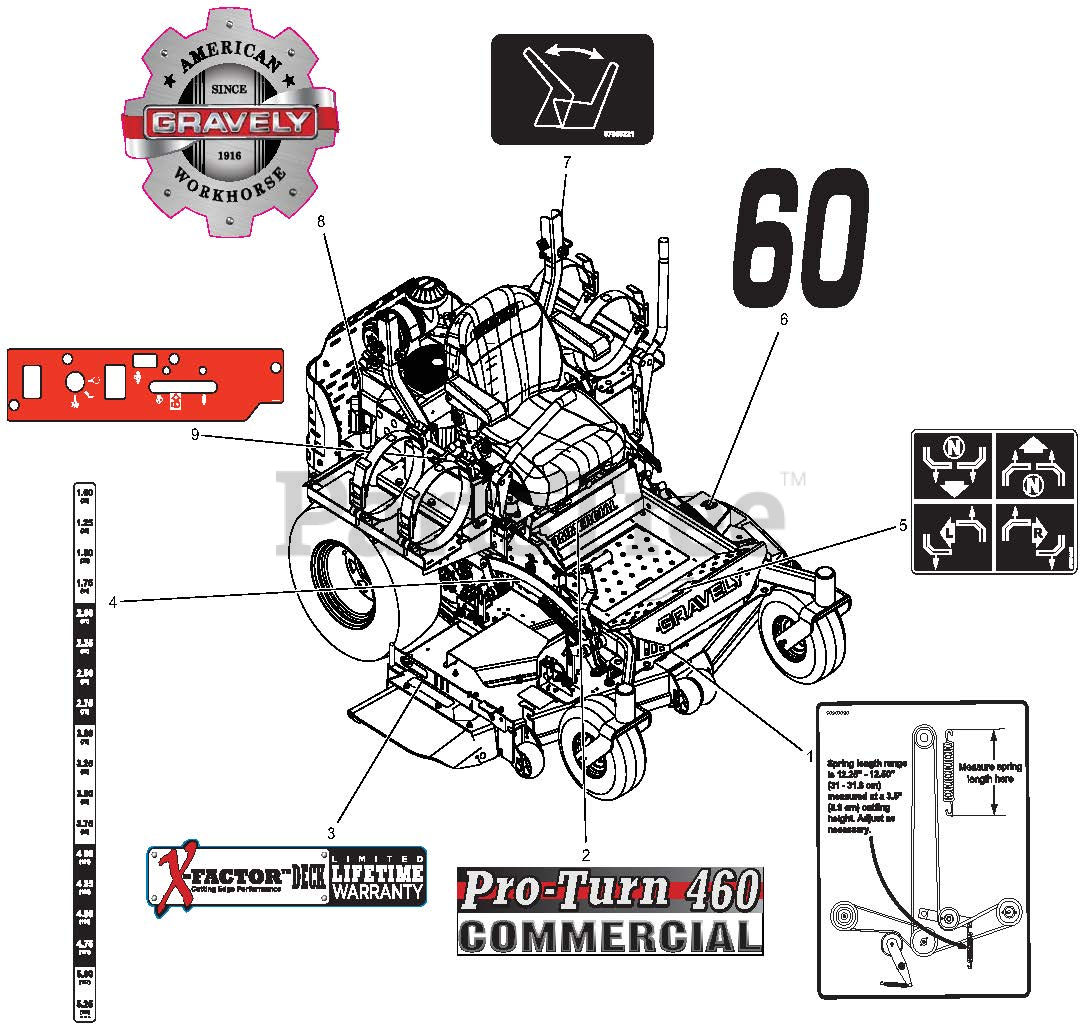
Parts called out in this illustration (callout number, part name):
1	DECAL, BELT DIAGRAM
2	DECAL, PT460
3	DECAL, X-FACTOR DECK
4	DECAL, PT400 HEIGHT OF CUT
5	DECAL, INSTRUCTIONAL - STEERING
6	DECAL, 60"
7	DECAL, SEAT RELEASE
8	DECAL, GRAVELY HERITAGE-LARGE
9	DECAL, CONTROL PT400 - LP
